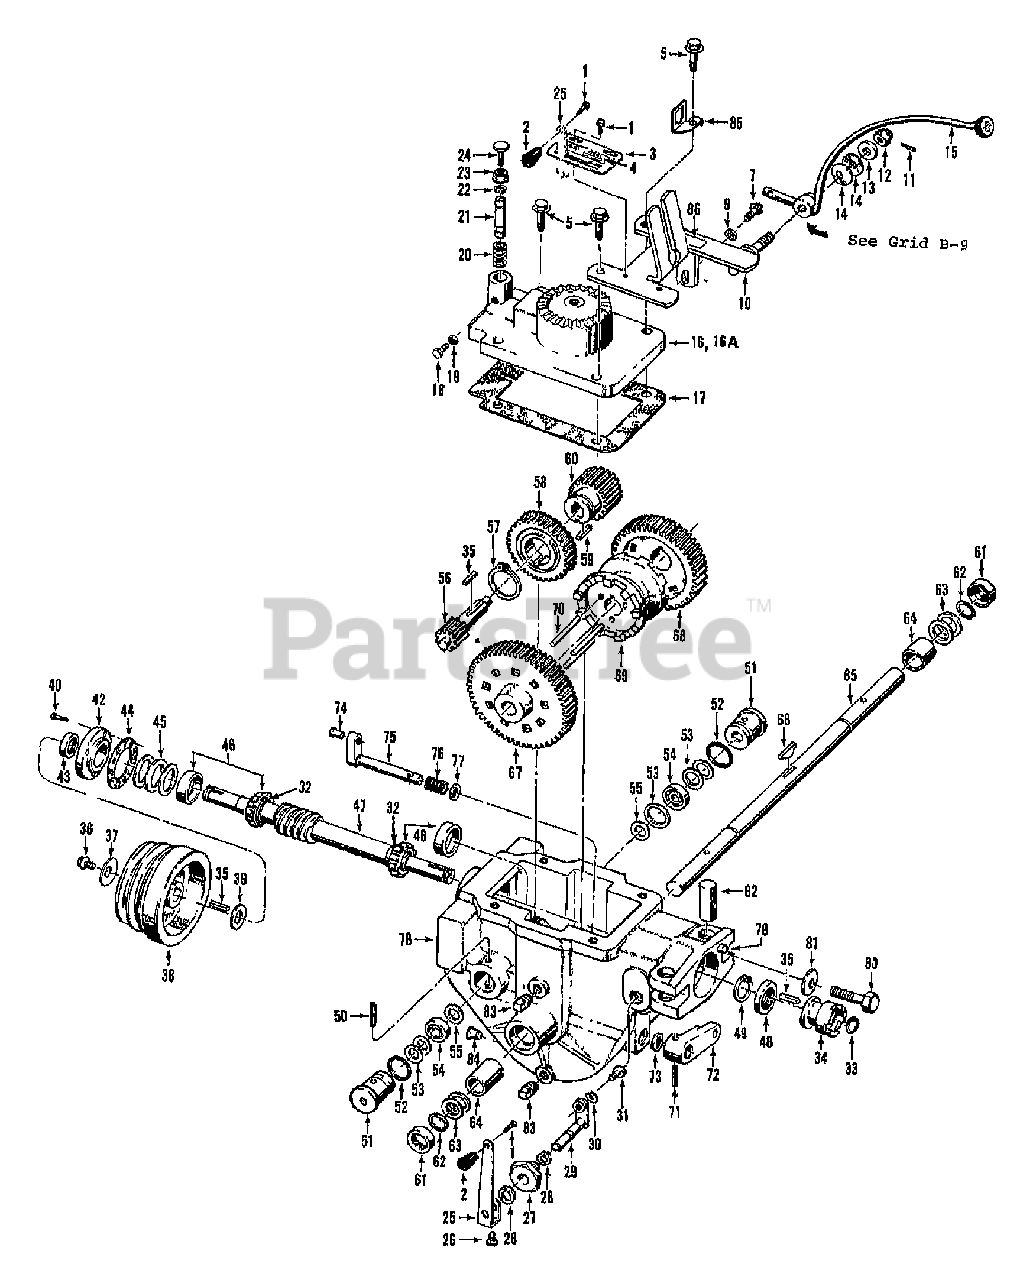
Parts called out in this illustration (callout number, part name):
1	SCR 10-32
2	KNOB-TAPERED
3	PLATE-TINE ENGAGE W/DECAL
4	DECAL-TINE ENGAGE
5	SCR-HFLK 3/8-16X1.50
6	THIS REF. NO. NOT USED
7	SCR-HFLK 5/16-18X.75 ZP
8	THIS REF. NO. NOT USED
9	WASHER-FLAT 5/16 SAE
10	BRKT-H HOOD 2149
11	PIN-SPRING .125 X 1
12	NUT-HEX 1/2-20
13	WASHER-# SHOULDER ZP
14	WASHER-# 1.97X1X.118
15	THIS REF. NO. NOT USED
16	COVER-TRANS RED 2523
16A	ASSM-TRANS COVER OPC
17	GASKET-TRANS COVER
18	SCR-HH 5/16-18X1.0 G5 ZP
19	NUT-HEX 5/16-18 ZP
20	SPRING-REV PLUNGER ZP
21	ASSM-NEUTRAL PLUNGER
22	RING-KLIP EXT .594 ID ZP
23	NUT-HFLK 3/8-16 ZP
24	SCR 3/8-16X1.5 UNC-2AG
25	LEVER-ECCENTRIC RED
26	SCR-HH 1/4-20X.5 GR5 YEL
27	BUSHING-.87X.5X.62 ECC
28	RING-RETAINING 5100-50
29	SHAFT-WELD ECCENTRIC
30	WASHER-LK .25 HI-COLLAR
31	SCR-HXSKT 1/4-20X.38 G8
32	SHIM-1.0X.7656X.062
33	RING-RETAIN EXT .707 ID
34	KIT-CLUTCH DOGS TILLER
34	CLUTCH-DOG HORSE TRANS
35	KEY-.188 SQX1.0
36	SCR-HH 5/16-24X.75 G5 ZP
37	WASHER-.827X.331X.098
38	PULLEY-TRANS MACH
39	WASHER-SHLDR HARDENED
40	SCR-HFLK 1/4-20X.75 G5 ZP
41	THIS REF. NO. NOT USED
42	COVER-FRONT
43	SEAL-PINION SHAFT PT/85030/00
44	GASKET-BRG COVER
45	SHIM-1.75X1.5X.01
45	SHIM-1.75X1.5X.03
45	SHIM-1.75X1.5X.005
45	SHIM-1.75X1.5X.062
46	KIT-BRG CONE&RACE-DRIVESHAFT
47	KIT-WHEELDRIVE ROLL/WORM
48	SEAL-OIL DRIVESHAFT
49	RING-RETAINING 5000-181
50	PIN-SPIROL .25 X 2.0
51	PLUG-PINION BRG W/RING
52	RING-O 1 ID
53	SHIM-1.234X1.015X.033
53	SHIM-1.234X1.015X.062
53	SHIM-1.234X1.015X.01
54	BRG-BALL (7 BALLS)
55	WASHER-# 1X.484X.06
56	GEAR-SPLINE 10 TEETH MACH
57	RING-RETAINING 5100-150
58	GEAR-WORM MACH
59	KEY
60	GEAR-SPUR 20 TEETH MACH
61	SEAL-OIL WHEELSHAFT
62	RING-HEAVY EXT .906 ID
63	SHIM-1.375X1.015X.062
63	SHIM-1.375X1.015X.03
63	SHIM-1.375X1.015X.015
63	SHIM-1.375X1.015X.01
63	SHIM-1.375X1.015X.005
64	BUSHING-1.25X1.005X1.5
65	KIT-WHEELSHAFT
66	KEY-HI PRO .25X1.812
67	GEAR-SPUR 56 TEETH MACH
68	GEAR-SPUR 46 TEETH MACH
69	CLUTCH-MACH
70	PIN-CLUTCH .25 2.65
71	PIN-SPIROL .188 X 1.25
72	LEVER-ECC. #1029
73	SEAL-OIL ECCENTRIC
74	PIN-.375 X .72
75	SHAFT-ECCENTRIC HORSE TLR
76	SPRING .845 X 1.25
77	WASHER # .875 X .65 X .06
78	CASE-TRANS W/PIN
79	PIN-DRIVE .375X.75 ZP
80	SCR-HH 1/2-13X2.0 G5 ZP
81	WASHER-DISC SPRING
82	POST (TC)
83	PLUG-PIPE 1/4 NPT
84	PLUG-CAP (RED)
85	CLIP-CONNECTOR
86	DECAL-FWD INTERLOCK WIRE
